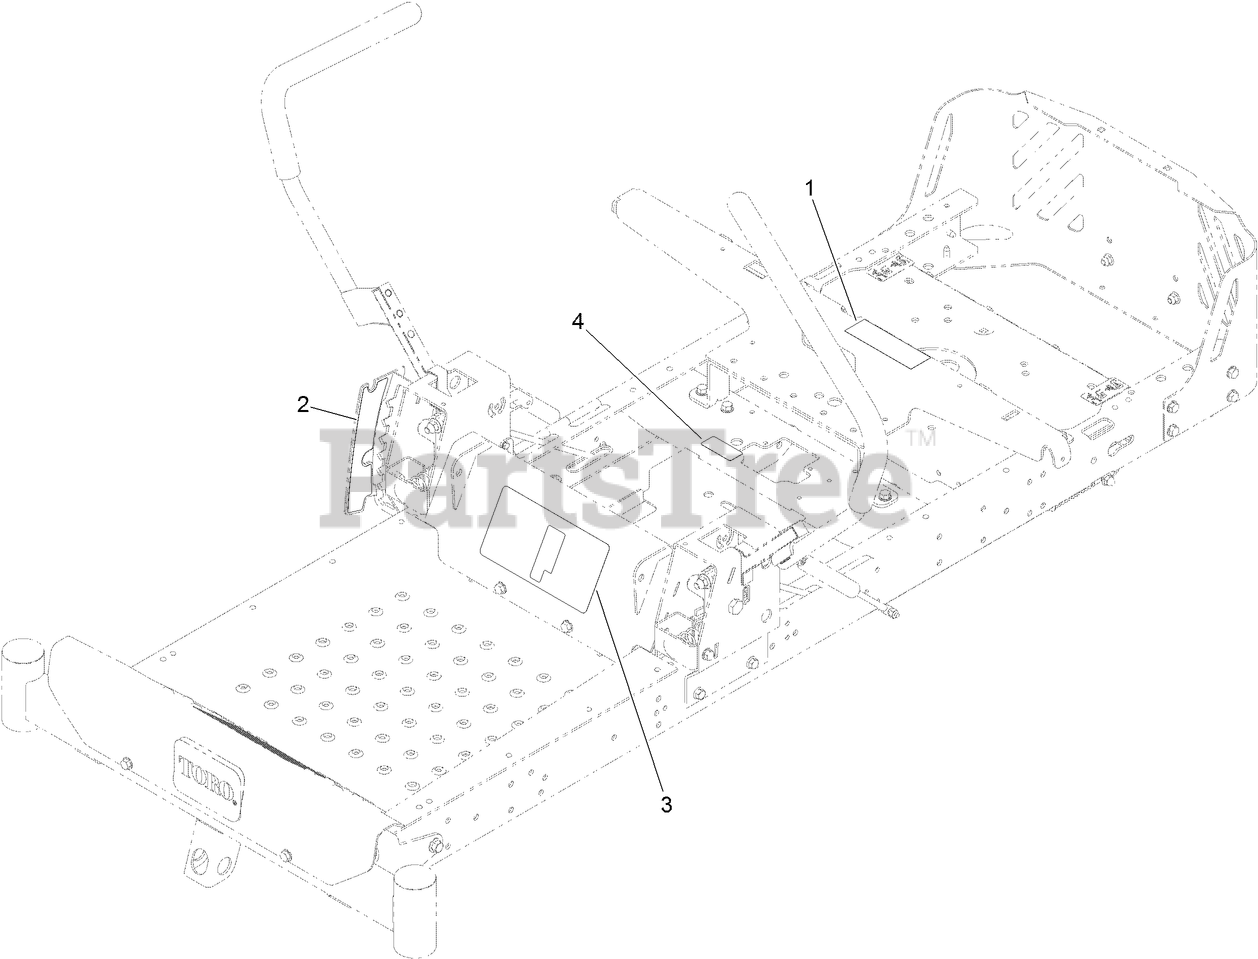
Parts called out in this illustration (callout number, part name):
1	DECAL-SERVICE, CE
2	DECAL-HOC
3	DECAL-CONTROL, SPEED
4	DECAL-LOCATION, SERVICE DEALER
